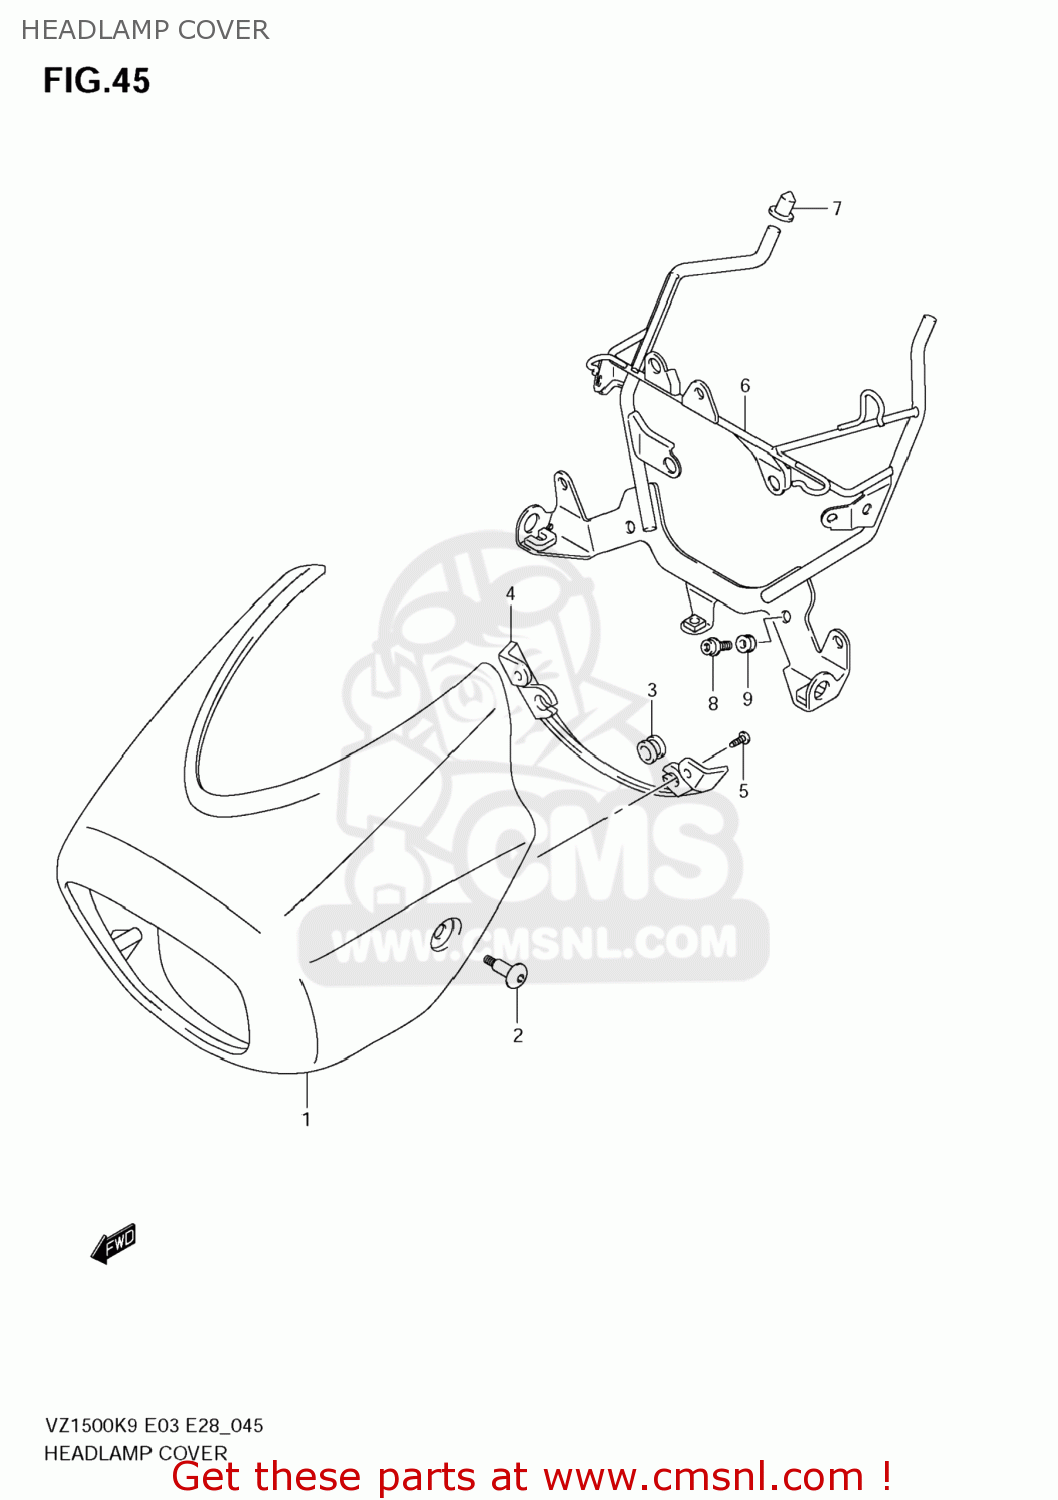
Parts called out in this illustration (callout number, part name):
1	COVER,HEADLAMP
2	SCREW,FUEL TAN
3	CUSHION
4	PLATE,HEADLAMP HOUSING
5	SCREW
6	BRACE,HEADLAMP COVER
7	CUSHION,HEADLAMP HOUSING BRACE
8	BOLT
9	CUSHION
